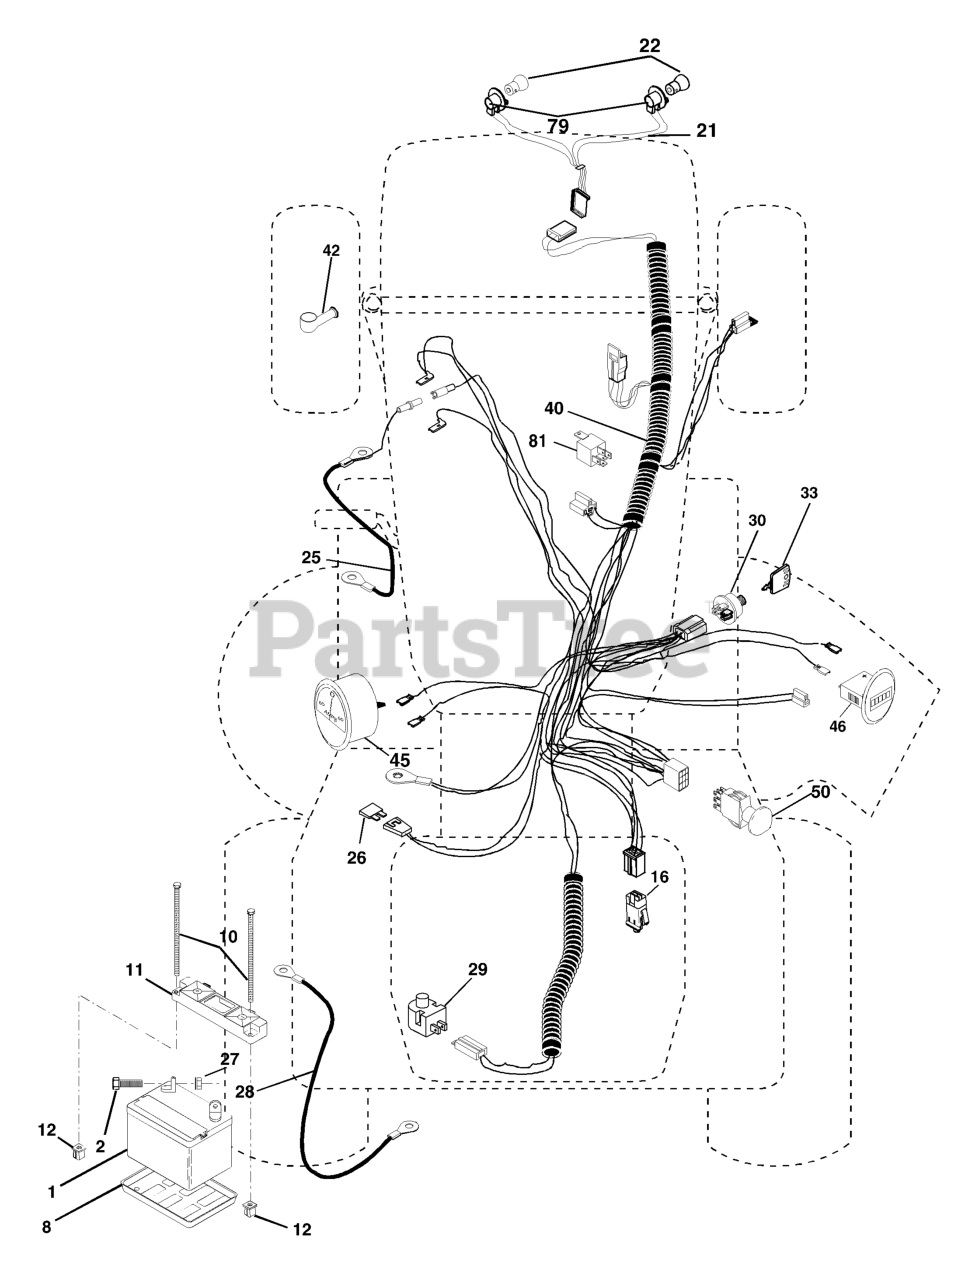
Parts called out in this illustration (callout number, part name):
1	BATTERY 12V .35 AMP
2	BOLT.HEX.1/4.X.3/4.DICHROMATE
8	BATTERY TRAY T
10	BOLT 1/4-20 X 7.5
11	BATTERY HOLDDOWN FRONT MOUNT
12	NUT, PUSH NYLON 1/4" BATTERY
16	SWITCH INTERLOOK PUSH-IN
21	HARNESS.W/LIGHT SOCKET
25	CABLE.4GA.RED.W/16GA.RED.WIRE
27	NUT
28	CABLE, GROUND
29	RP.SWITCH.PLUNGER.NC.GRAY
30	IGNITION SWITCH
33	KEY MLD GEN DELTA
40	HARNESS.IGNITION.VGT.NO.RELAY
42	COVER.TERMINAL.RED
45	RP AMMETER.ROUND.SILVER.DELTA
46	RP HOURMETER SNAP-IN
50	RP.PTO.SWITCH.8 TERMINAL.BLACK
79	BULB HOLDER ASM.
81	RELAY.ASSY.T
